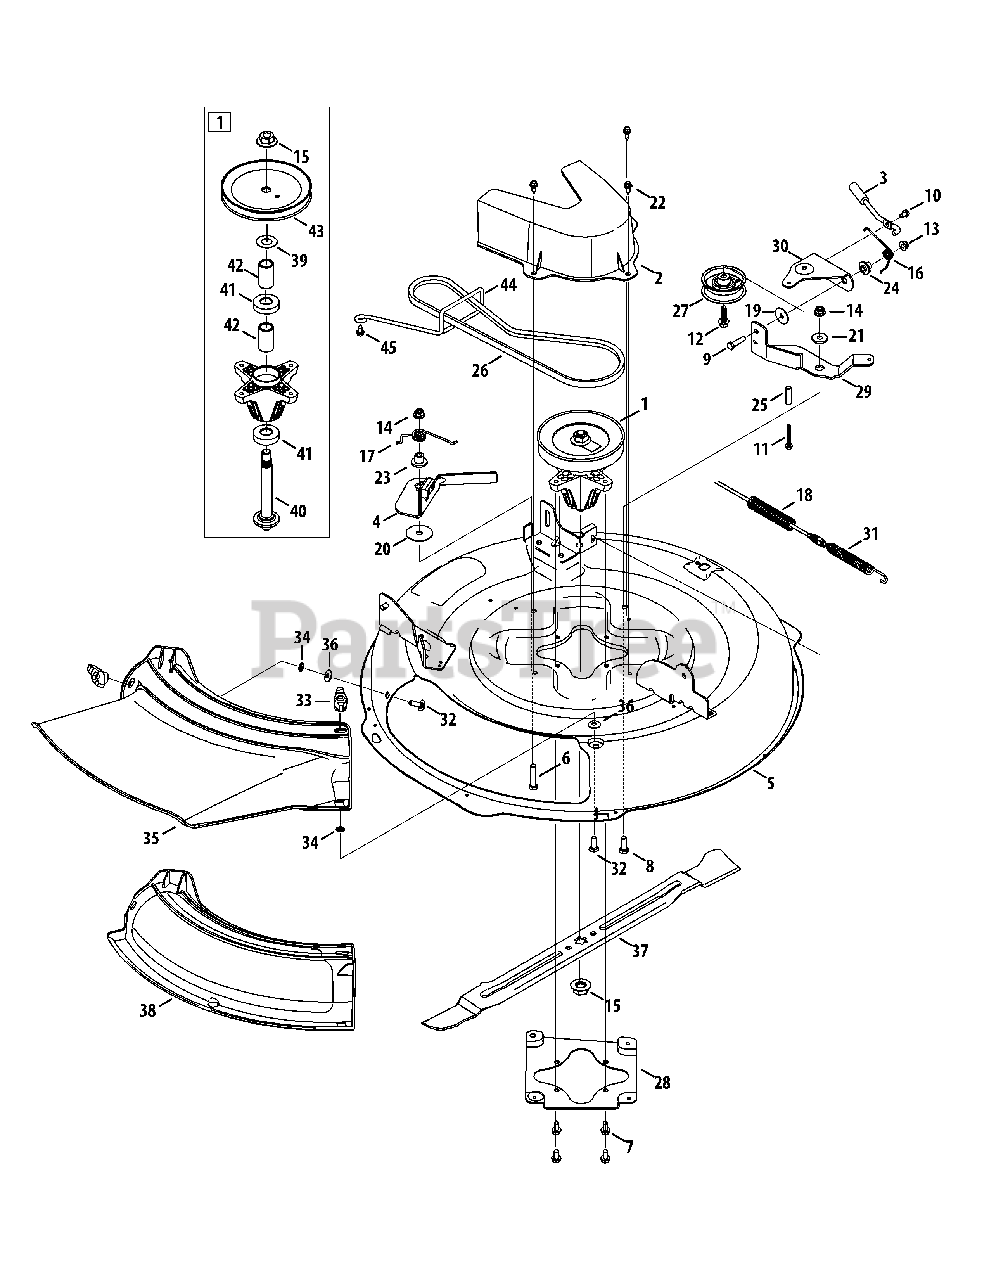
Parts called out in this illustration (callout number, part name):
1	Spindle Pulley Assembly 6.3 Dia.
2	Deck Belt Cover
3	Idler Rod Assembly
4	PTO Brake Assembly Bracket
5	Deck, 30" w/out Nozzle
6	Hex Cap Screw, 3/8-16 x 1.75
7	Tap Screw 5/16-18 x .750
8	Hex Head Screw 3/8-16 x 1.00
9	Hex Cap Screw 5/16-18 x 1.25
10	Tap Scew, 1/4-20, 0.500
11	Tap Screw 1/4-20 x 1.750
12	Tap Screw 3/8-16 x 1.250
13	Flange Lock Nut 5/16-18
14	Flange Lock Nut 3/8-16
15	Flange Nut 5/8-18
16	PTO Torsion Spring
17	Brake Torsion Spring
18	Compression Spring .625 x 4.0
19	Flat Washer .330 x 1.250 x .060
20	Flat Washer .406 x 1.920 x .060
21	Shoulder Spacer .625 ID x .169
22	Shoulder Screw .368 x.113: 1/4-20
23	Shoulder Spacer .625 ID x .169
24	Shoulder Spacer .134 x .500 x .438
25	Spacer .260 x .372 x 1.420 LG
26	V-Type Belt 5L, 43.5 Lg.
27	Flat Idler Pulley 2.75 OD
29	Lower Floating Idler Bracket
30	Upper Floating Idler Bracket
31	PTO Cable
32	Carriage Screw 5/16-18 x 1.00
33	Wing Knob 5/16-18
34	Speed Nut .3125 ID
35	Chute Deflector
36	Cupped Washer .340 x .872 x .060
37	Cutting Blade 30.00" 3-IN-1
38	Mulch Plug (optional)
39	Shim Washer .760 x 1.500 x .030
40	Spindle Shaft 6.11 Lg.
41	Ball Bearing .787 ID x 1.85 OD x .551
42	Spacer .792 x 1.060 x 1.860 Lg.
43	Deck Pulley 6.3 DIA
44	Belt Keeper
45	Hex Wash TT Scr. 1/4-20 x .625
